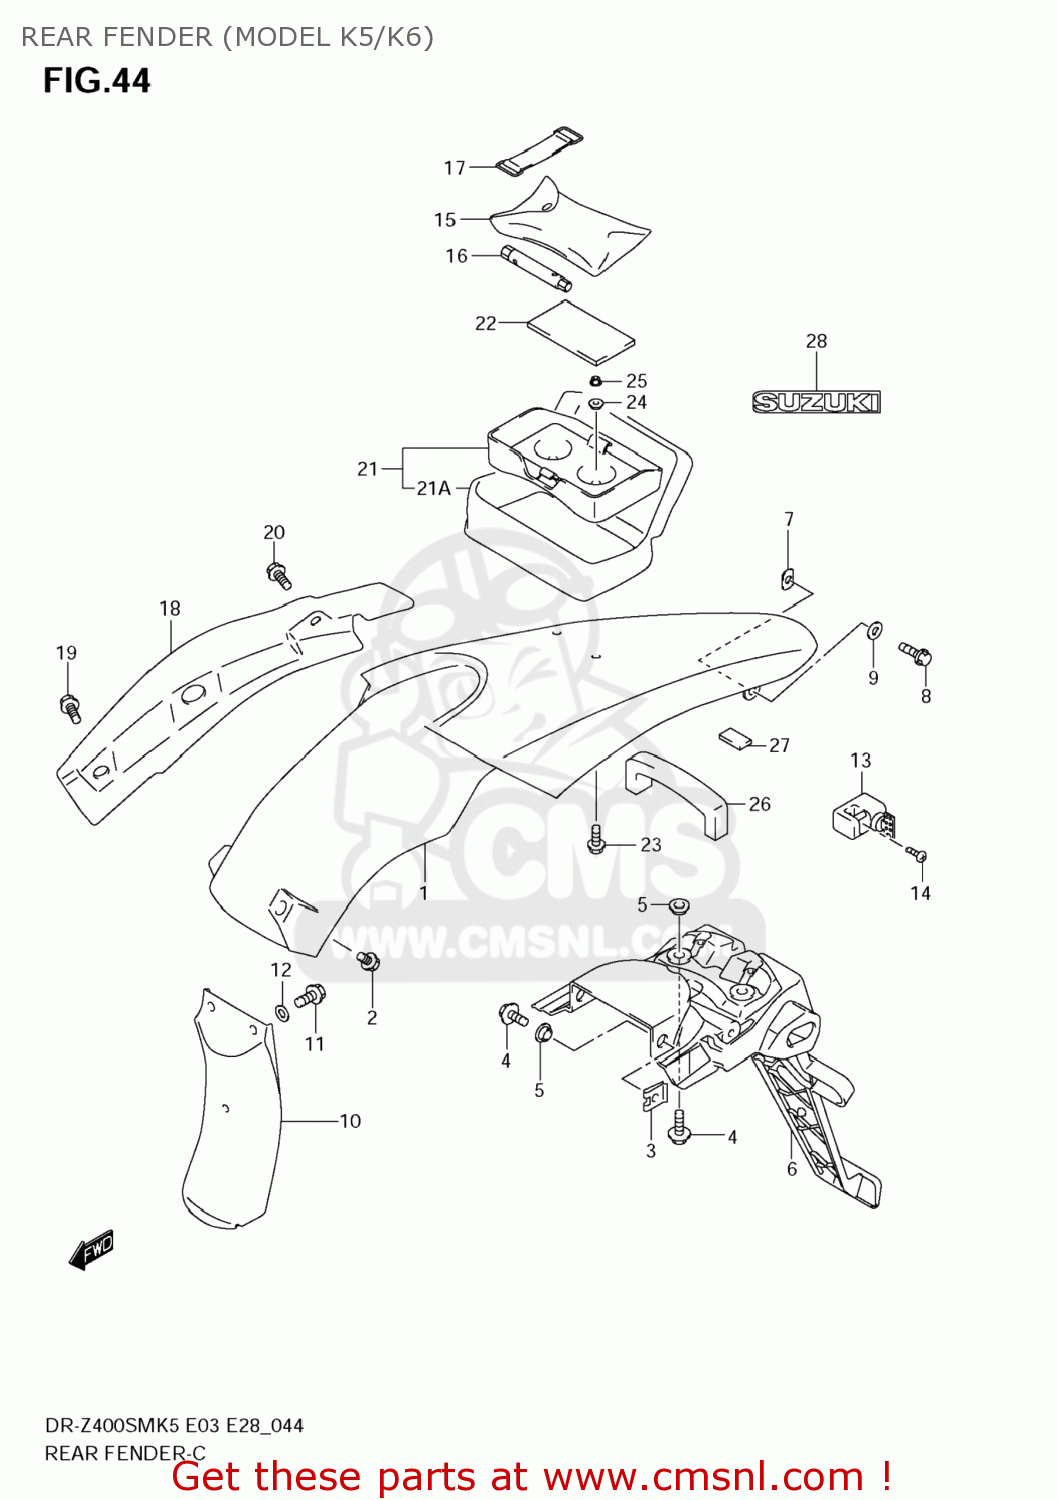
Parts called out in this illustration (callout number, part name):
1	FENDER,REAR
2	BOLT(6X16)
3	PLATE,REAR FENDER FITTING
4	BOLT(6X20)
5	WASHER
6	EXTENSION,REAR
7	NUT,COWL
8	BOLT
9	WASHER (5X14X1)
10	MUDGUARD,RR FENDER FR
11	BOLT
12	WASHER
13	LOCK SET,HELMET
14	SCREW(6X14)
15	TOOL ASSY
16	SPARK PLUG WRENCH(8X10)
17	BAND
18	MUDGUARD,RR FENDER,R
19	BOLT(6X18)
20	BOLT
21	BAG ASSY,SEAT TAIL
21A	BAG,SEAT TAIL
22	CUSHION,RR BAG
23	BOLT
24	WASHER
25	NUT
26	SEALER,SIDE COVER L
27	PROTECTOR(170X95X3.0)
28	EMBLEM,SUZUKI
